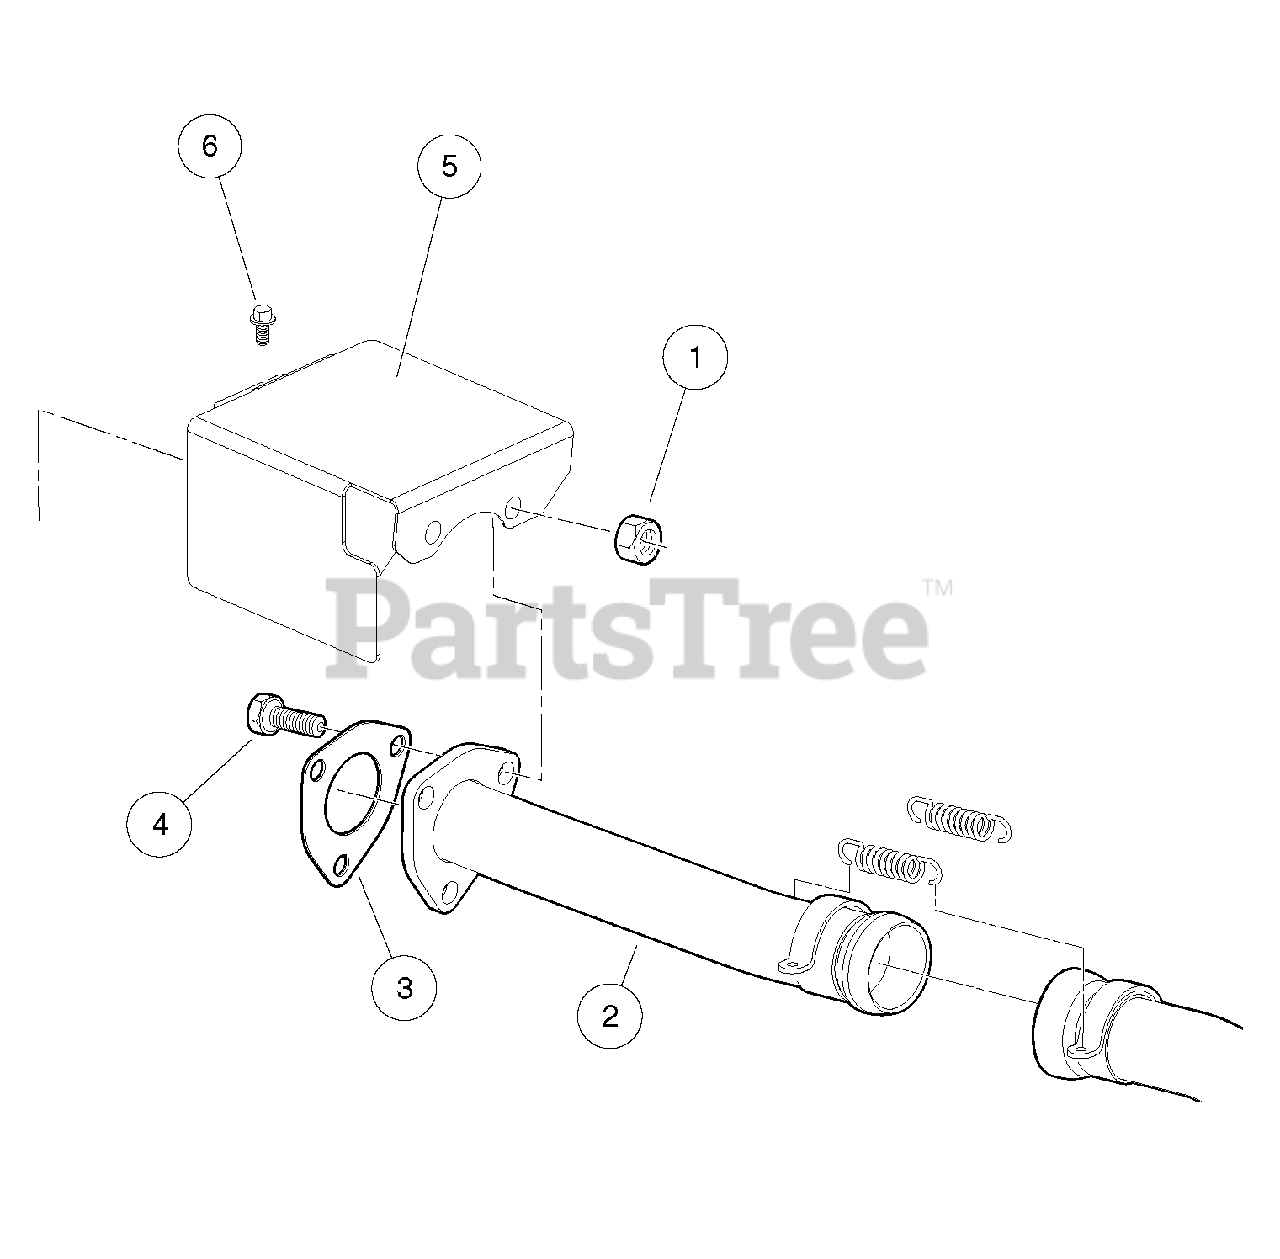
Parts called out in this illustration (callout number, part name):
1	Nut,m8,all Metal Lock
2	Pipe, Exhaust Diesel Main
3	Gasket, Exhaust Diesel
4	Bolt, M8 X 1.25 X 40 with Loctite
5	Shield, Diesel Exhaust
6	Bolt, D722, Exhst Manfld Cover
